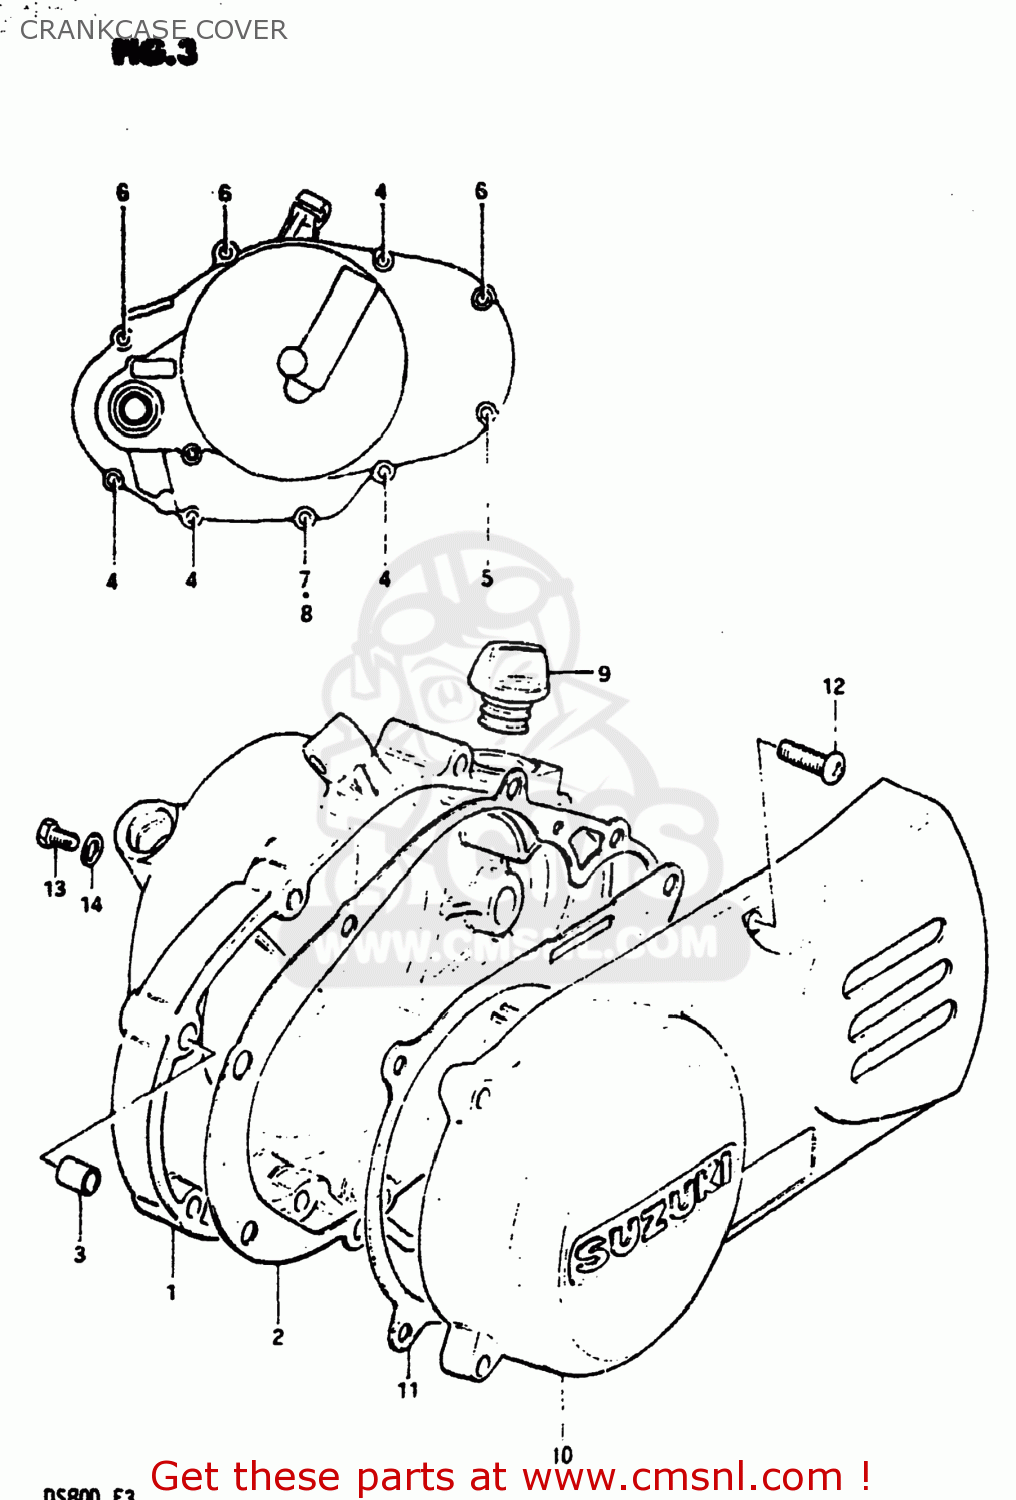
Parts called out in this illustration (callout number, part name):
1	COVER,CLUTCH
2	GASKET,CLUTCH COVER (MCA)
3	PIN
4	SCREW
5	SCREW
6	SCREW
7	SCREW
8	GASKET(6.2X11X1).2 (NAS)
9	PLUG
10	COVER,MAGNETO
11	GASKET,MAGNETO COVER (NAS)
12	SCREW
13	SCREW(6X10)
14	GASKET(6.2X11X1) (NAS)
